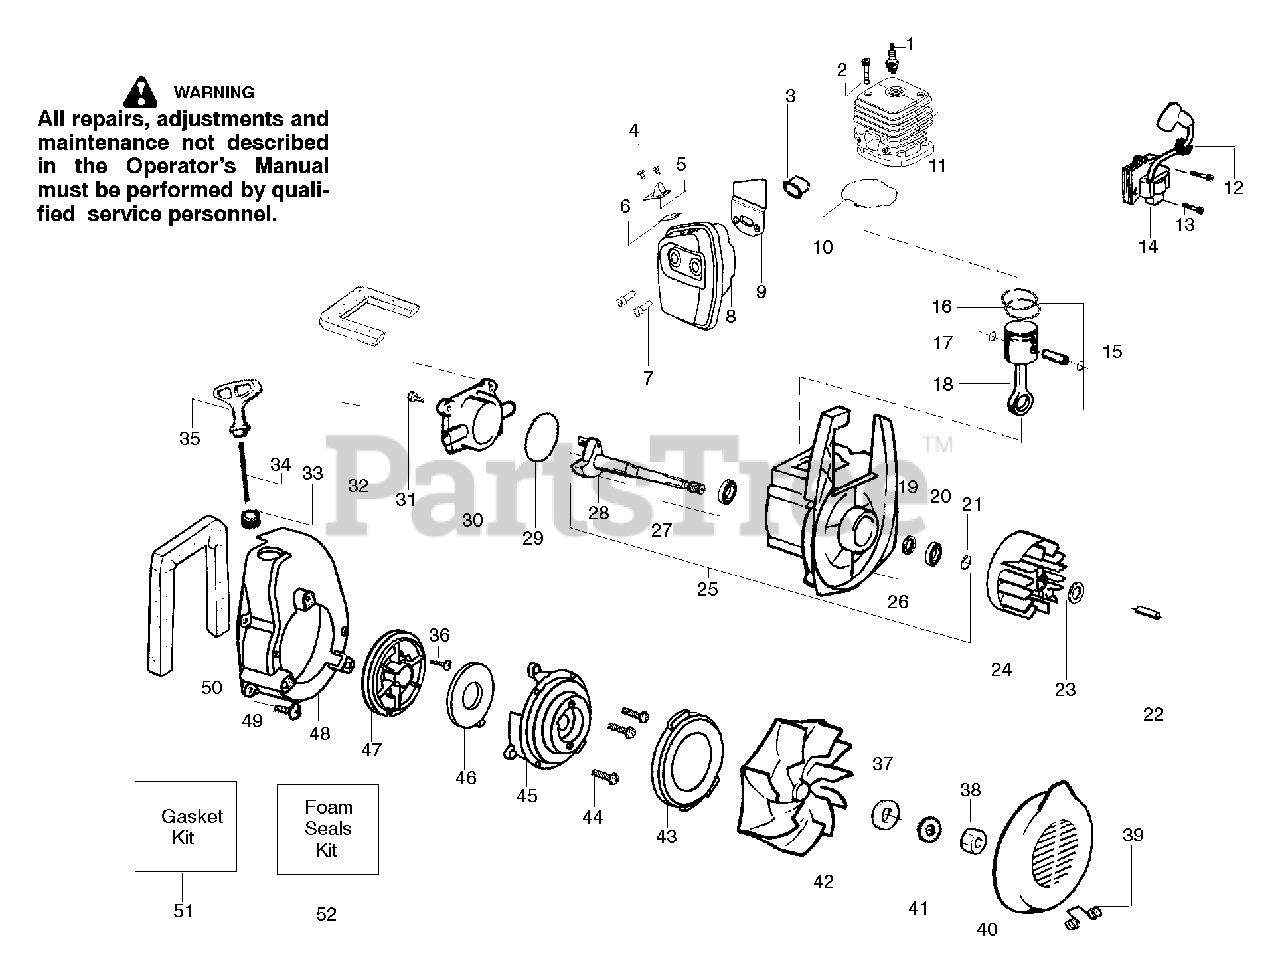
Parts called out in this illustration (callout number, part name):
1	Spark Plug (RCJ-6Y)
3	Insulator-Heat
5	Deflector-Muffler
6	Kit-Spark Screen
7	Screw-Muffler-Internal
8	Kit-Muffler
9	Gasket-Baffle
10	Gasket-Cylinder
11	Kit-Cylinder
12	Grommet-Ign. Module
13	Screw-Ignition Module
14	Ignition Module
15	Kit-Piston
16	Piston Ring
17	Retainer-Piston Pin
18	Assy-Connecting Rod
19	Seal-Crankcase
20	Bearing-Outer
21	Retainer Ring-C'chaft
22	Spacer-Flywheel
24	Assy-Flywheel
25	Assy-Crankcase/Crankshaft
26	Assy-Crankcase
27	Bearing-Inner
28	Assy-Crankshaft
29	O-ring-C/case-Shroud
30	Cover-Crankcase
31	Screw
32	Foam-219mm (kit)
33	Eyelet-Flange
34	Kit-Rope
35	Handle-Starter
36	Screw-Rope
37	Washer-Flat
39	Spring-Return Cover
40	Inlet Door
41	Washer-Belleville
42	Assy-Impeller
43	Seal-Ring
45	Housing-Pulley
46	Spring-Starter
47	Kit-Starter Pulley
48	Fan Housing
49	Screw
50	Foam-365mm (kit)
51	Kit-Gasket
52	Kit-Foam Seals
